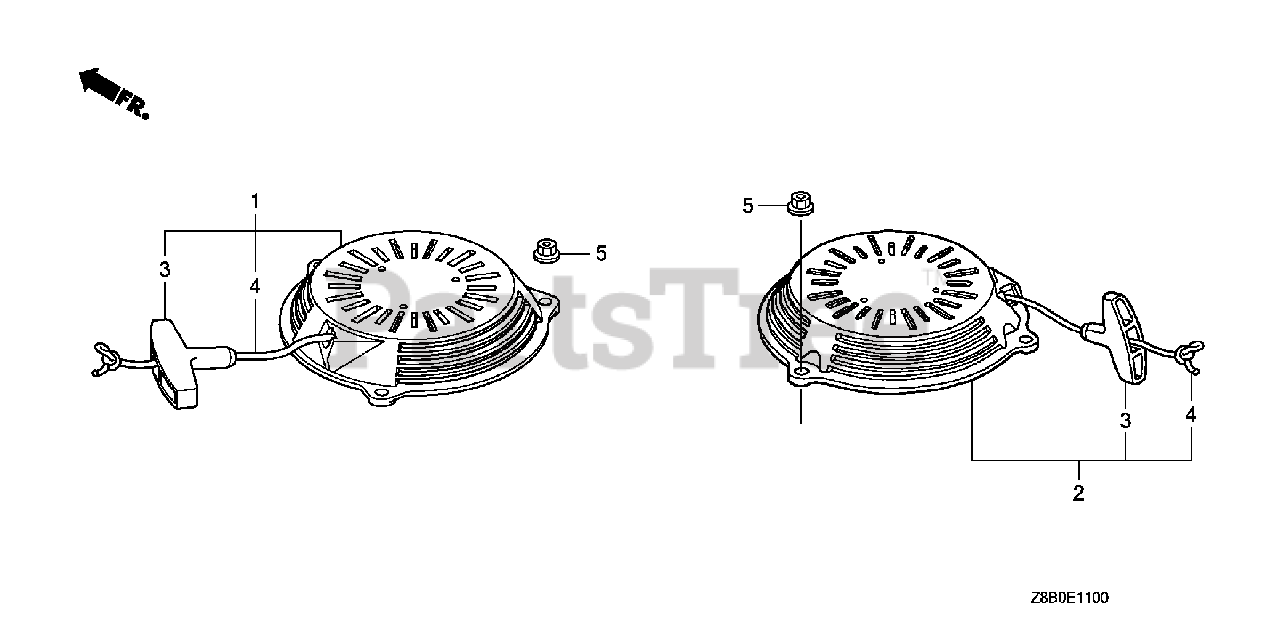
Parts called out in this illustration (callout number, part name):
2	STARTER ASSY., RECOIL *NH1* (LONG ROPE) (BLACK)
2	STARTER ASSY., RECOIL *R280* (LONG ROPE) (POWER RED)
3	GRIP, STARTER
4	ROPE, RECOIL STARTER (LONG TYPE)
5	NUT, FLANGE (6MM)
